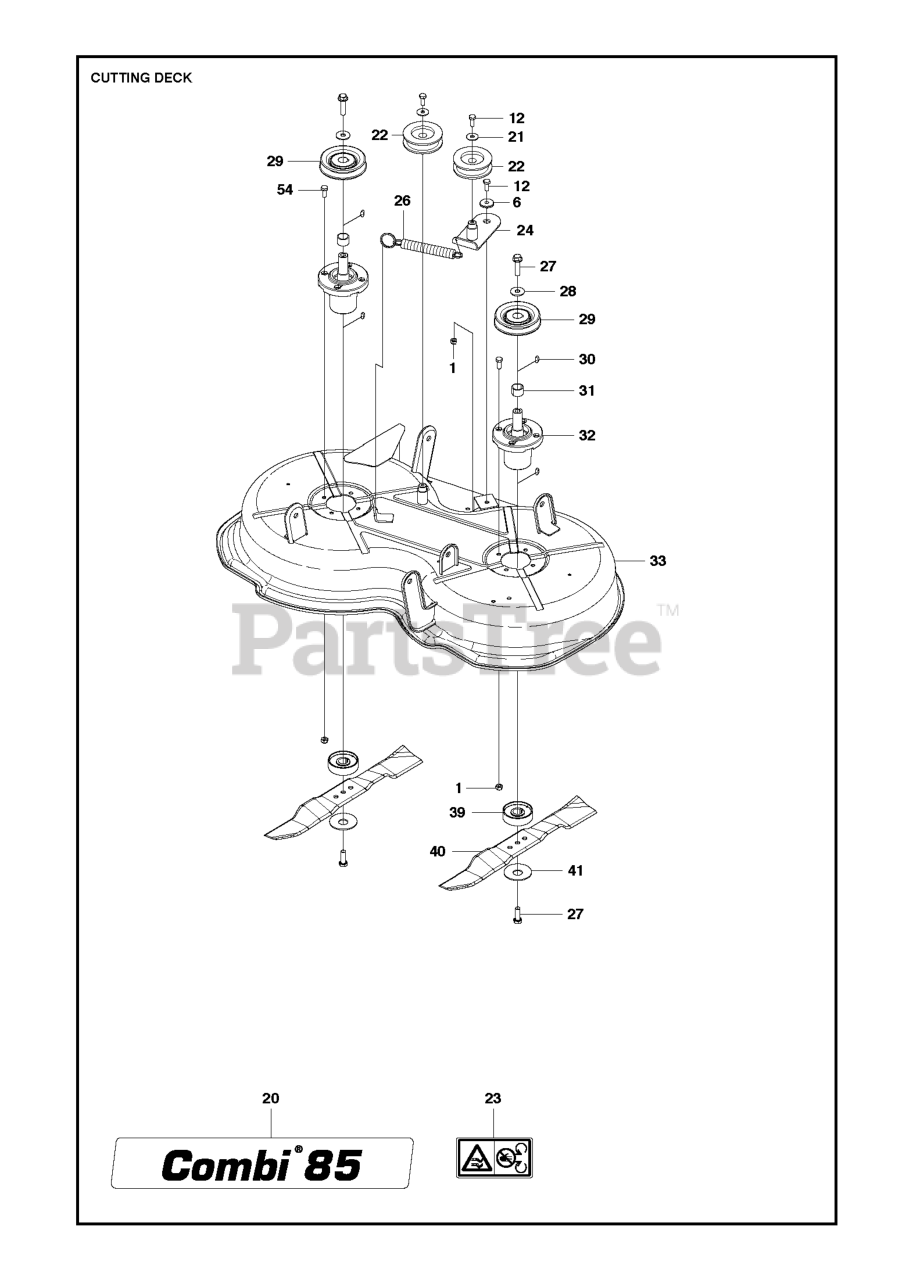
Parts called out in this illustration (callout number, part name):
1	LOCKNUT M8
6	WASHER
22	PULLEY
